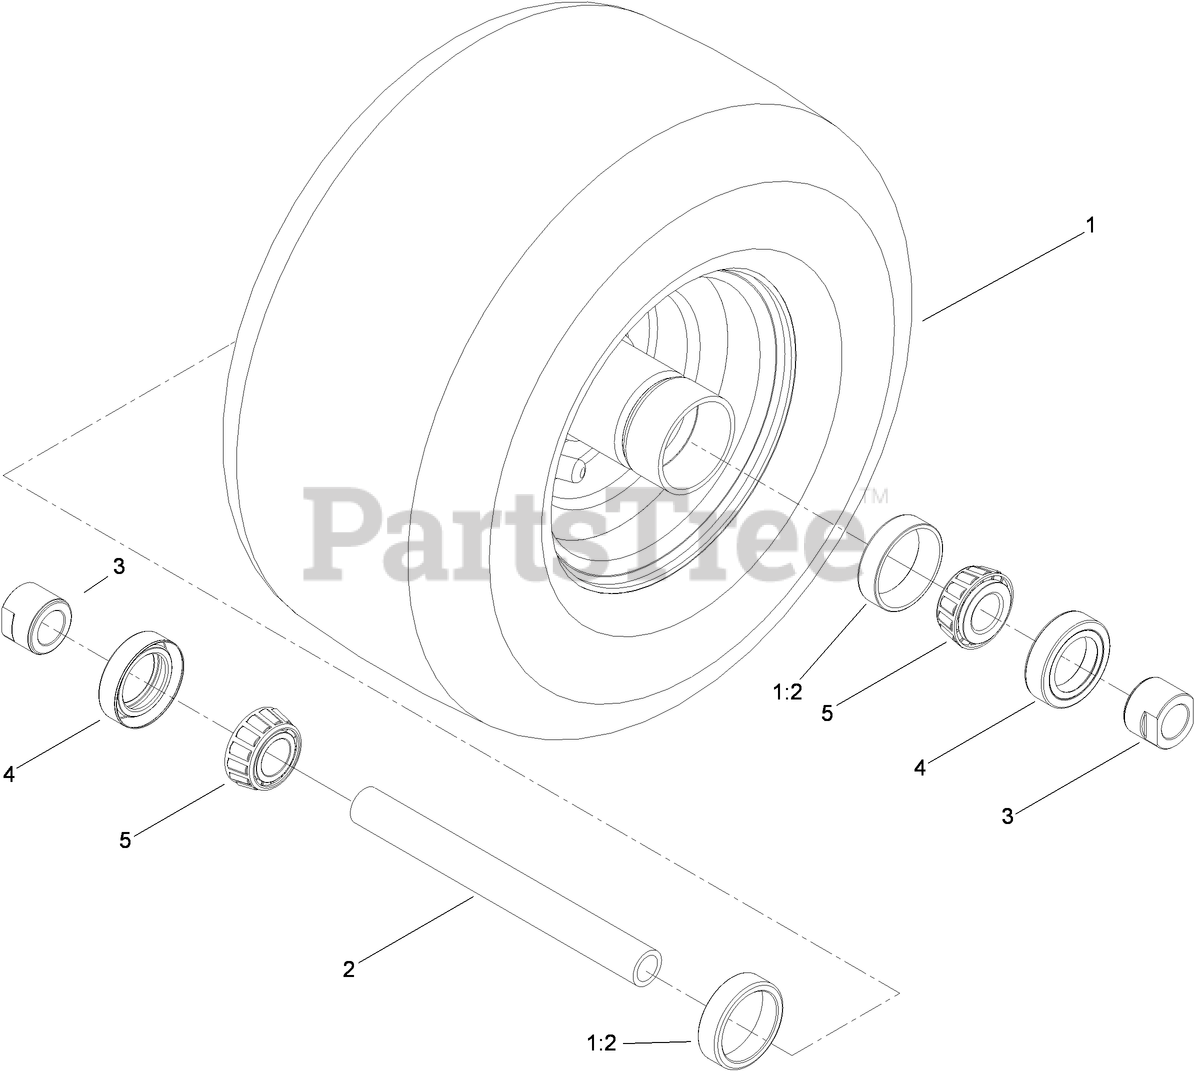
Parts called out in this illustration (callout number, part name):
1	WHEEL AND TIRE ASM
1:2	BEARING-CUP
2	AXLE-CASTER
3	SPACER-NUT
4	SEAL-CASTER
5	BEARING-CONE, TAPER
